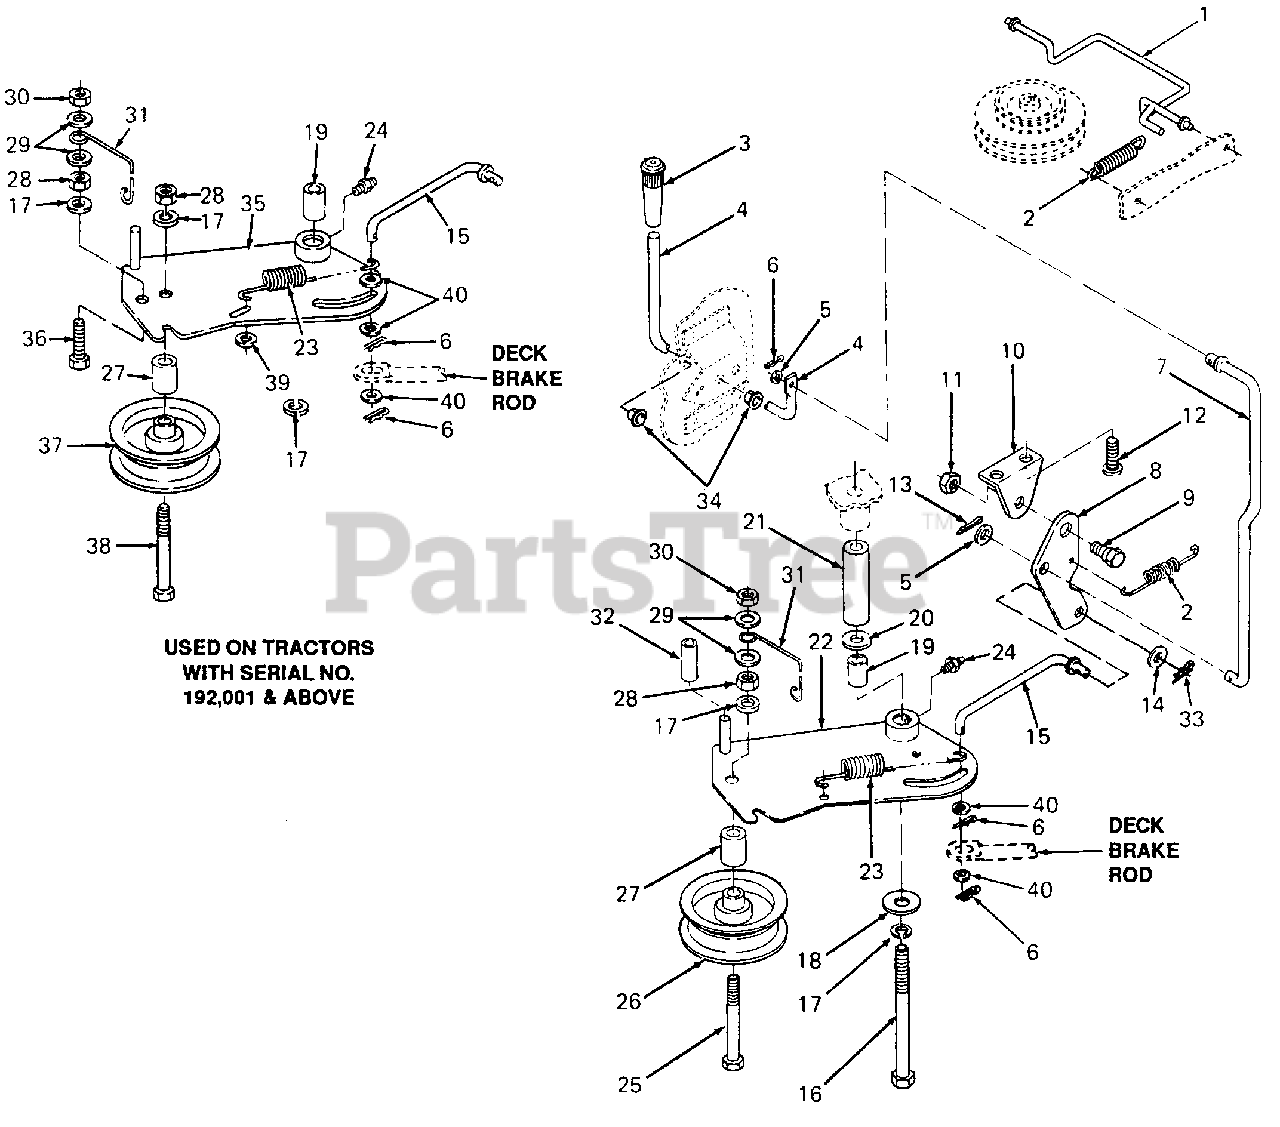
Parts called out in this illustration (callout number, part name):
1	Guard, Belt
2	Spring, Extension
4	Handle, PTO Clutch
5	Washer, Flat, .344 X .875 X .06 Thk
6	Pin, Internal Cotter, 5/16 Dia
7	Rod, PTO Clutch
10	Bracket, Pivot
11	Nut, Hex Center Lock, 5/16-18 GR5
12	Screw, Truss Phillips Hd, 5/16-18 X 1.0 Lg
13	Pin, Cotter, 1/16 Dia X .75 Lg
14	Washer, Flat, .281 X .73 X .063 Thk
15	Rod, Clutch
16	Bolt, Hex, 3/8-16 X 4.75 Lg GR5
17	Washer, Lock, 3/8
18	Washer, Flat, .406 X 1.25 X .157 Thk
19	Spacer, .3776 X .500 X .830 Lg
20	Washer, Flat, .385 X .87 X .06 Thk HDN
21	Spacer, Idler, .385 X .75 X 2.68 Lg
22	Bracket, Manual Idler Arm
23	Spring, Extension, .58 OD X 2.90 Lg
24	Fitting, Lube, 3/16 Drive
25	Screw, Hex Cap, 3/8-16 X 3.0 Lg GR8
26	Idler, Flat
27	Spacer, .38 X .75 X .88 Lg
28	Nut, Hex, 3/8-16 GR5
29	Washer, Flat, .406 X .75 X .06 Thk
30	Nut, Hex Center Lock Jam, 3/8-16
31	Guard, Belt
32	Line, Fuel, 1.31 Lg
33	Pin, Internal Cotter
34	Bushing, Nyliner
35	Bracket, Manual Idler Arm
36	Screw, Hex Cap, 3/8-16 X 1.25 Lg GR5
37	Idler, Flat
38	Screw, Hex Cap, 3/8-16 X 2.5 Lg GR5
39	Washer, Flat, .218 X .62 X .063 Thk
40	Washer, Flat, .28 X .72 X .030 Thk
